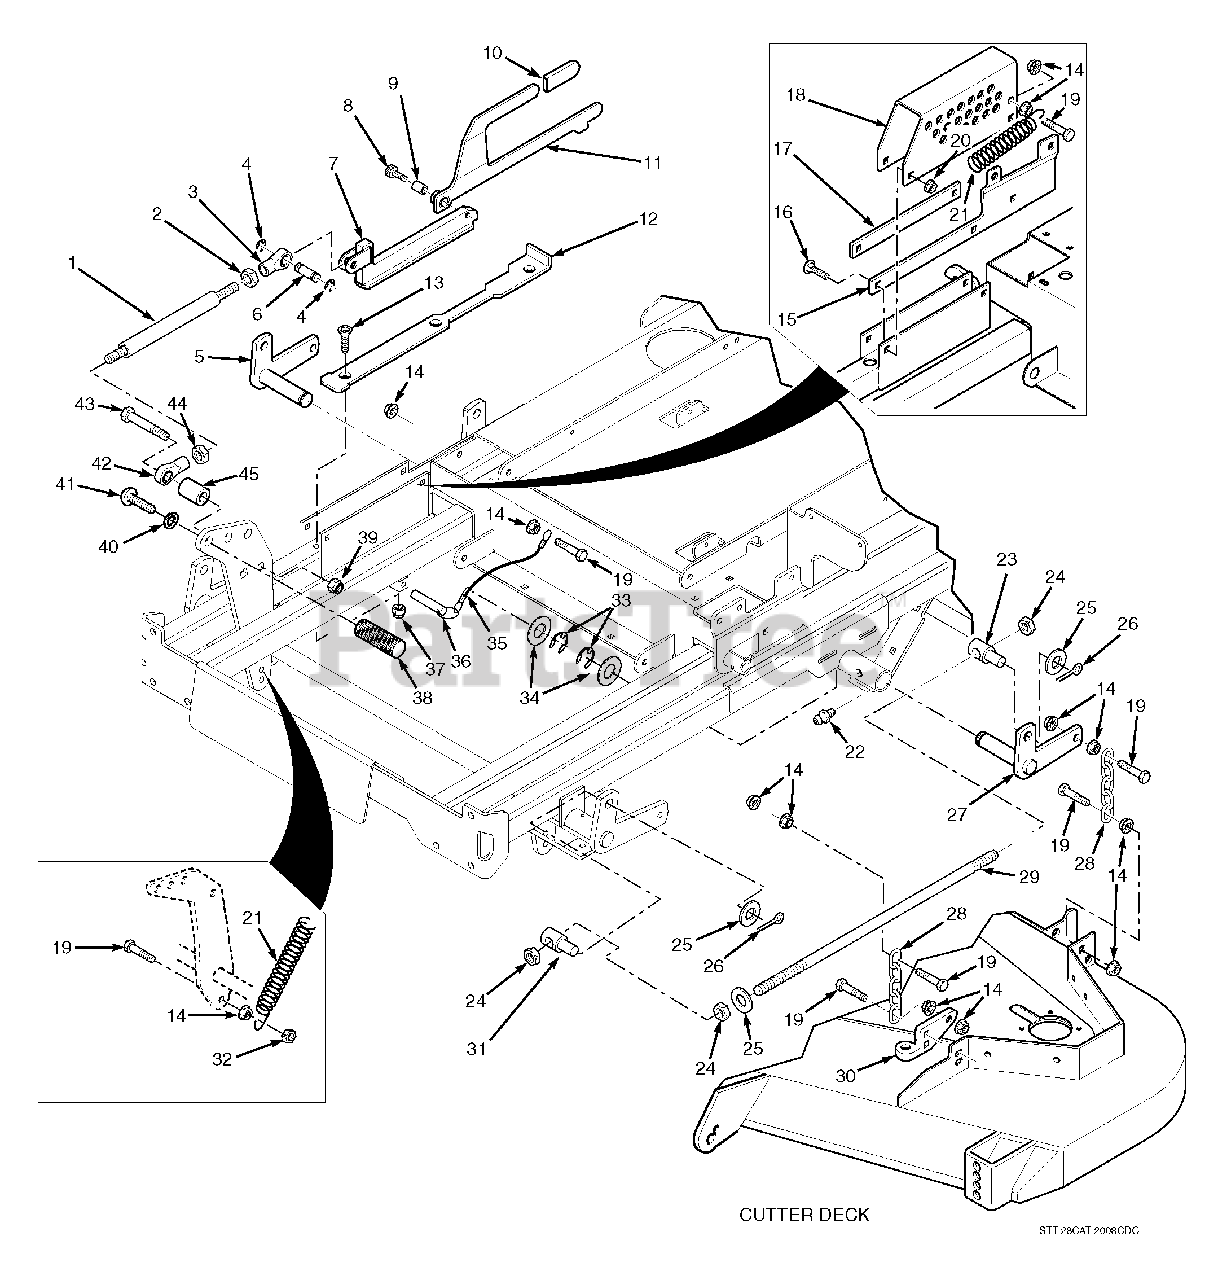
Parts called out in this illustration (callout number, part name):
1	Link, Deck Lift
2	Nut, Jam 1/2-20 LH
3	Rod End, Female - 1/2-20 LH
4	Ring, Retaining 1/2" External "E"
5	Bellcrank Weldment, RH Rear
6	Pin, Decklift
7	Slide Weldment, Height Adjustment
8	Bolt, Shoulder 1/2 x 3/4"
9	Bushing, .502 ID.
10	Grip, Deck Latch
11	Deck Latch
12	Lockplate, Decklift
13	Screw, Cap 5/16-18 x 3" FHHS
14	Nut, Hex Serrated Flange 3/8-16
15	Guide, Long
16	Bolt, Carriage 5/16-18 x 1"
17	Guide, Short
18	Bracket, Cutting Height Adjustment
19	Bolt, Hex Head 3/8-16 x 1-1/2"
20	Nut, Hex Serrated Flange 5/16-18
21	Spring, Helper
22	Grease Fitting
23	Swivel Joint, LH
24	Nut, Hex 5/8-11
25	Flatwasher, 5/8" (.656 x 1.312 x .095)
26	Cotter Pin, 3/16 x 1"
27	Bellcrank Weldment, LH Rear
28	Chain
29	Stud, 5/8-11 x 26.0"
30	Lever Assembly, Deck Level
31	Swivel Joint, RH
32	Locknut, 3/8-16 Center Lock
33	Ring, Retaining 1" External "E"
34	Flatwasher, 1" (1.062 x 1.50 x .048)
35	Lanyard, Deck Height Pin
36	Ring Pin, 1/2 x 3.06"
37	Nut, 3/8-16 Elastic Stop
38	Foot Pedal, Height Adjustment
39	Nut, Hex Elastic Stop 1/2-13
40	Lockwasher, 5/8"
41	Capscrew, 5/8-11 x 1-1/2"
42	Rod End, Female - 1/2-20 RH
43	Bolt, Hex Head 1/2-13 x 3"
44	Nut, Jam 1/2-20 RH
45	Spacer, Decklift Pedal
